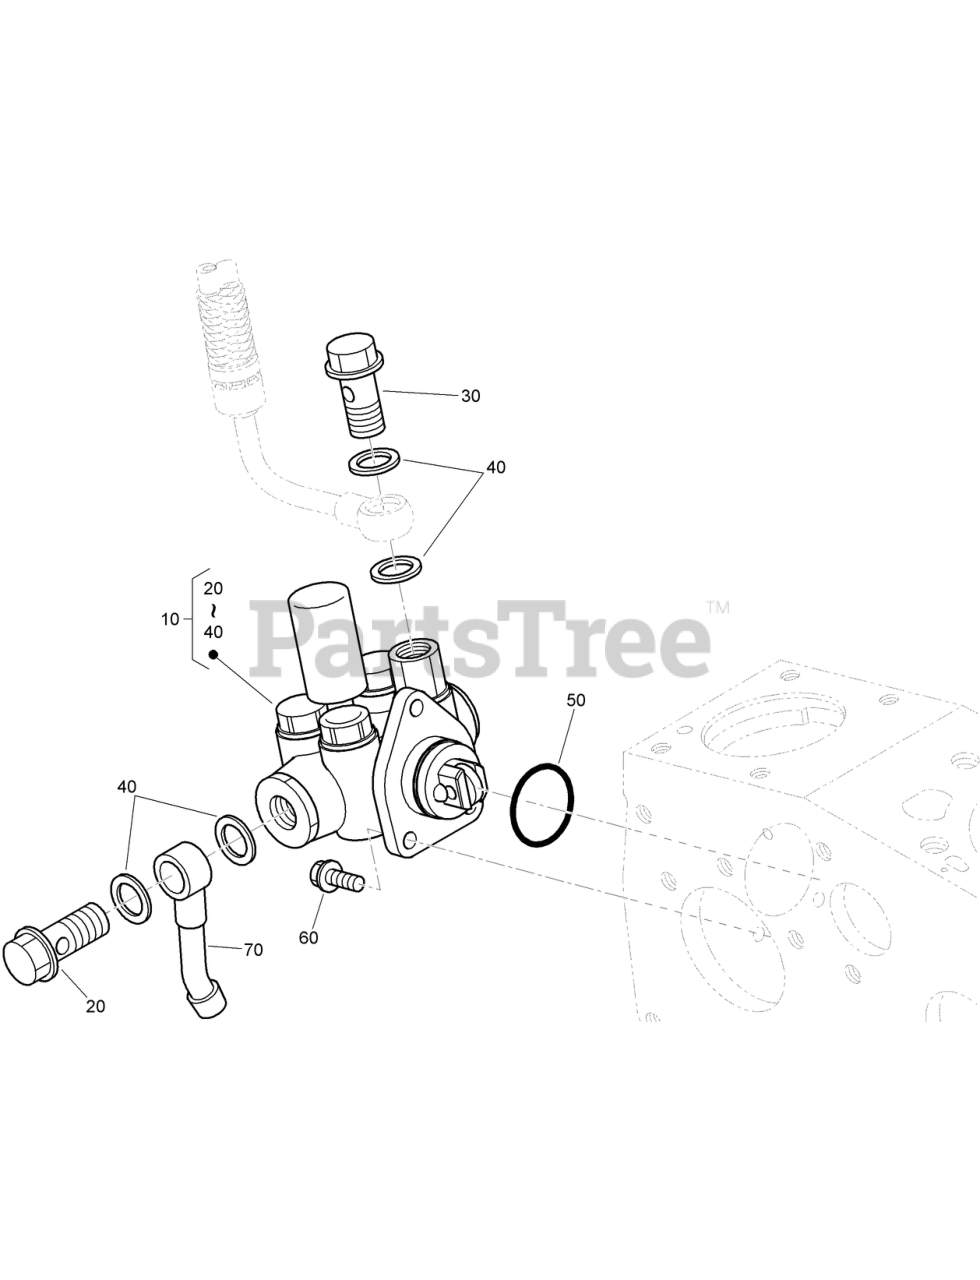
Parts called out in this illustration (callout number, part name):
10	FUEL PUMP ASM
20	BOLT-JOINT
30	BOLT-JOINT
40	GASKET-JOINT, PIPE
50	O-RING
60	BOLT-FLANGE
